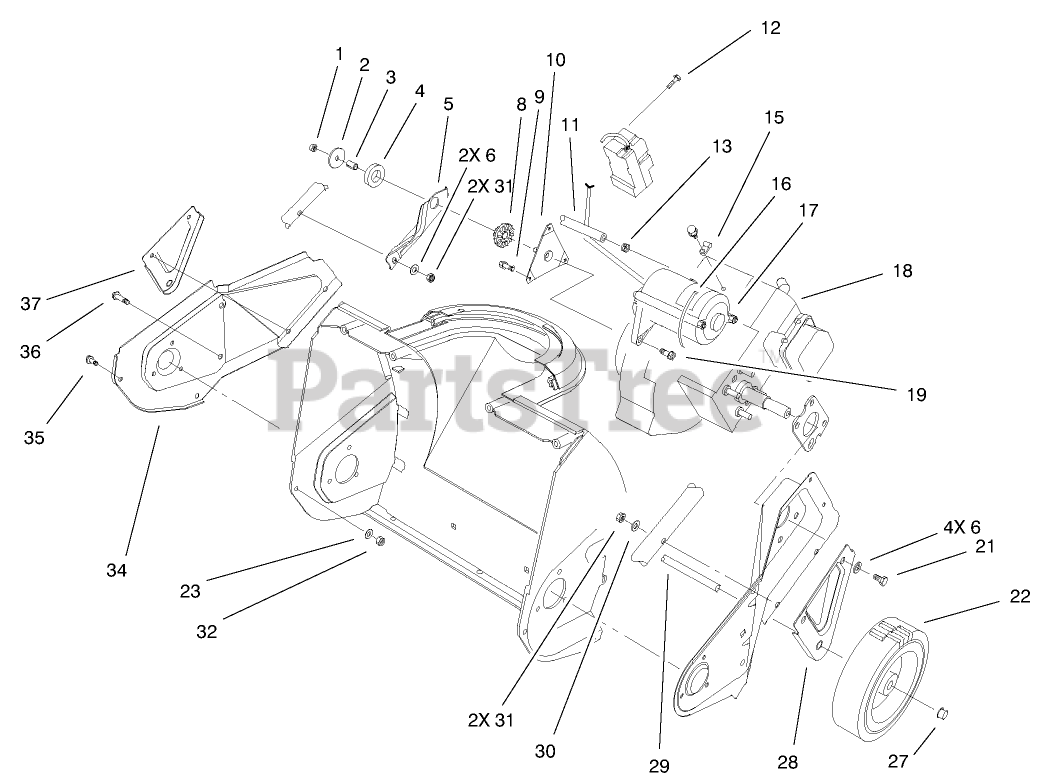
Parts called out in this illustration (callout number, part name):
1	NUT-LOCK, NI
3	SPACER-TUBULAR
4	RING-ISOLATOR
5	BRACKET-SUPPORT, ENGINE
6	WASHER-FLAT
8	BUSHING-ISOLATOR
9	SCREW
10	BRACKET AND STUD ASM
11	LINE-GAS
12	SCREW-PLASTITE
13	CLAMP-HOSE
15	CLAMP
16	TIE-CABLE
19	SCREW-HH, TORX
21	SCREW-HH
22	WHEEL
23	WASHER-FLAT
27	NUT-PUSH
28	BRACKET-WHEEL, LH
29	AXLE SHAFT
30	WASHER
31	NUT-LOCK, NI
32	NUT-LOCK, NI
34	PLATE-SIDE, RH
36	SCREW-PLASTIC
37	BRACKET-WHEEL, RH
